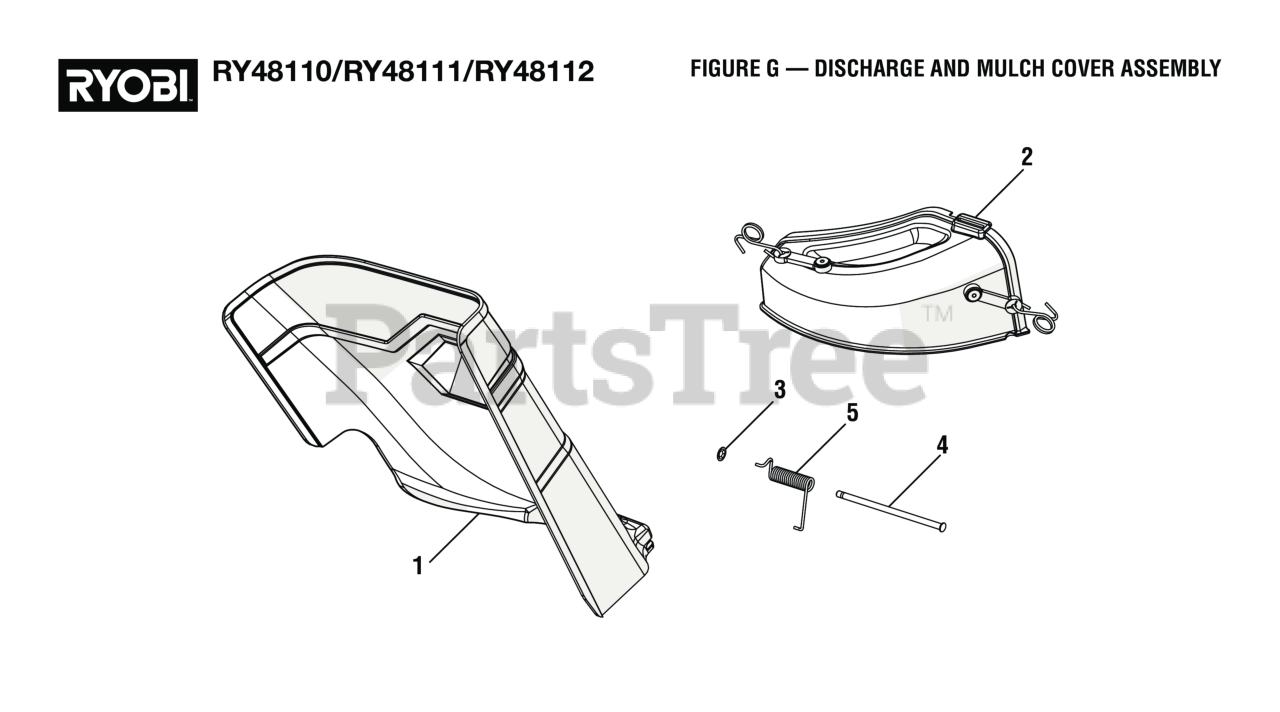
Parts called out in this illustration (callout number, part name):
1	Grass Deflector
2	Mulch Cover Kit
3	Retainer Clip
4	Hinge Pin (7.85 x 175.85)
5	Torsion Spring (19 x 62 x 3.02t)
